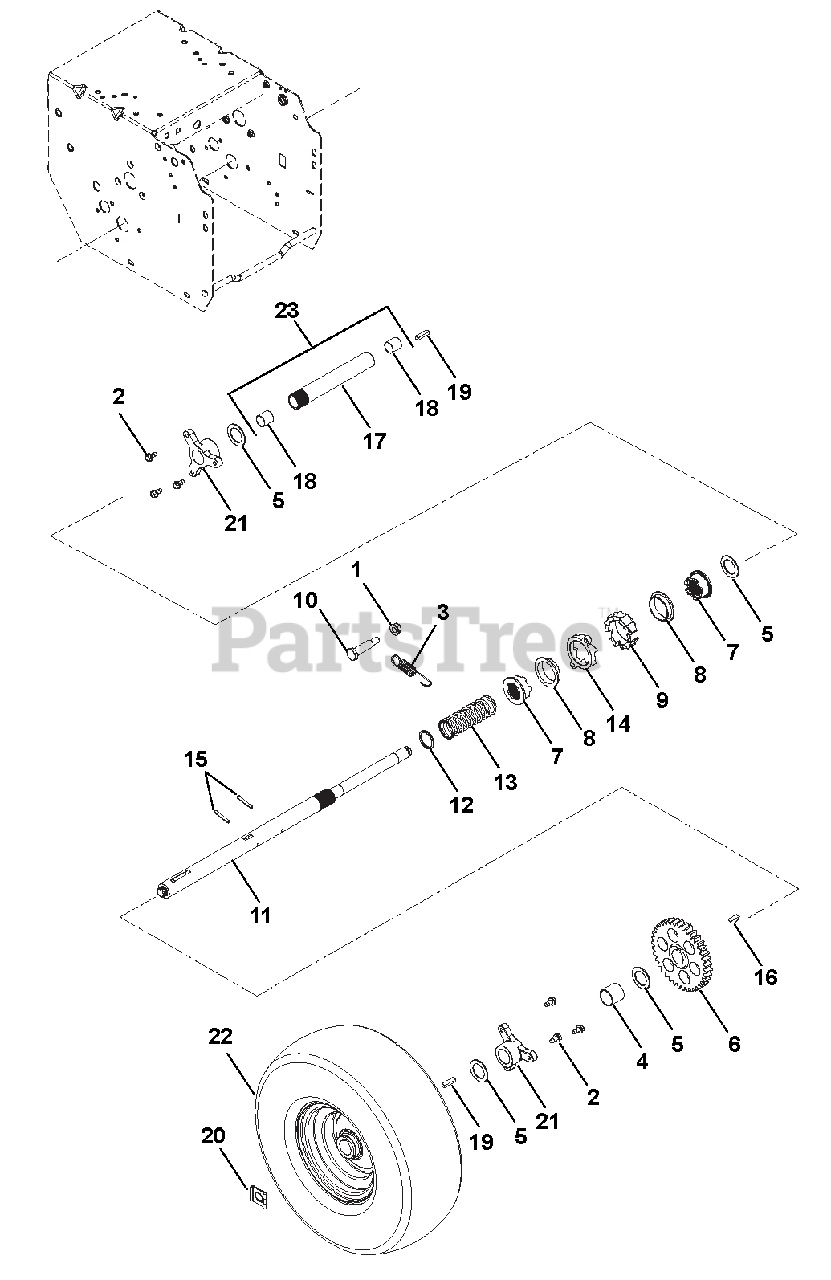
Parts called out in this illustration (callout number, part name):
1	@NUT-LK-TOP-FLG .38-16 YWZC
2	SCR-TAP .25-20X.50 HWH TR YWZ
3	SG-TENS .06X.62X2.94
4	BSHG-SLV, 1.012X1.125X1.00
5	WSHR-FL-STL 1.010X1.505X.062YZ
6	GEAR, SPUR
7	CLUTCH, DOG - SLIDING
8	BUSHING, FLANGE
9	GEAR, RATCHET
10	BLT-SHLDR .50X1.52 .38-16X.635
11	AXLE, LONG - CLICKER
12	WSHR-FL-STL 1.010X1.250X.068YZ
13	SPRING, COMPRESSION
14	GEAR, CLUTCH
15	PIN-ROLL .188X1.25
16	KEY-WDRF .25X.750X.313 SAE91
17	AXLE, SHORT - CLICKER
18	BSHG-SLV .706X.764X.75 BRZ
19	KEY-RECT .25X.188X1.00
20	CLIP, SNAP .625 DIA
21	BUSHING, AXLE
22	TIRE/WHEEL,15X5-6 REMOTE K398A
23	AXLE, CLICKER W/BUSHINGS
